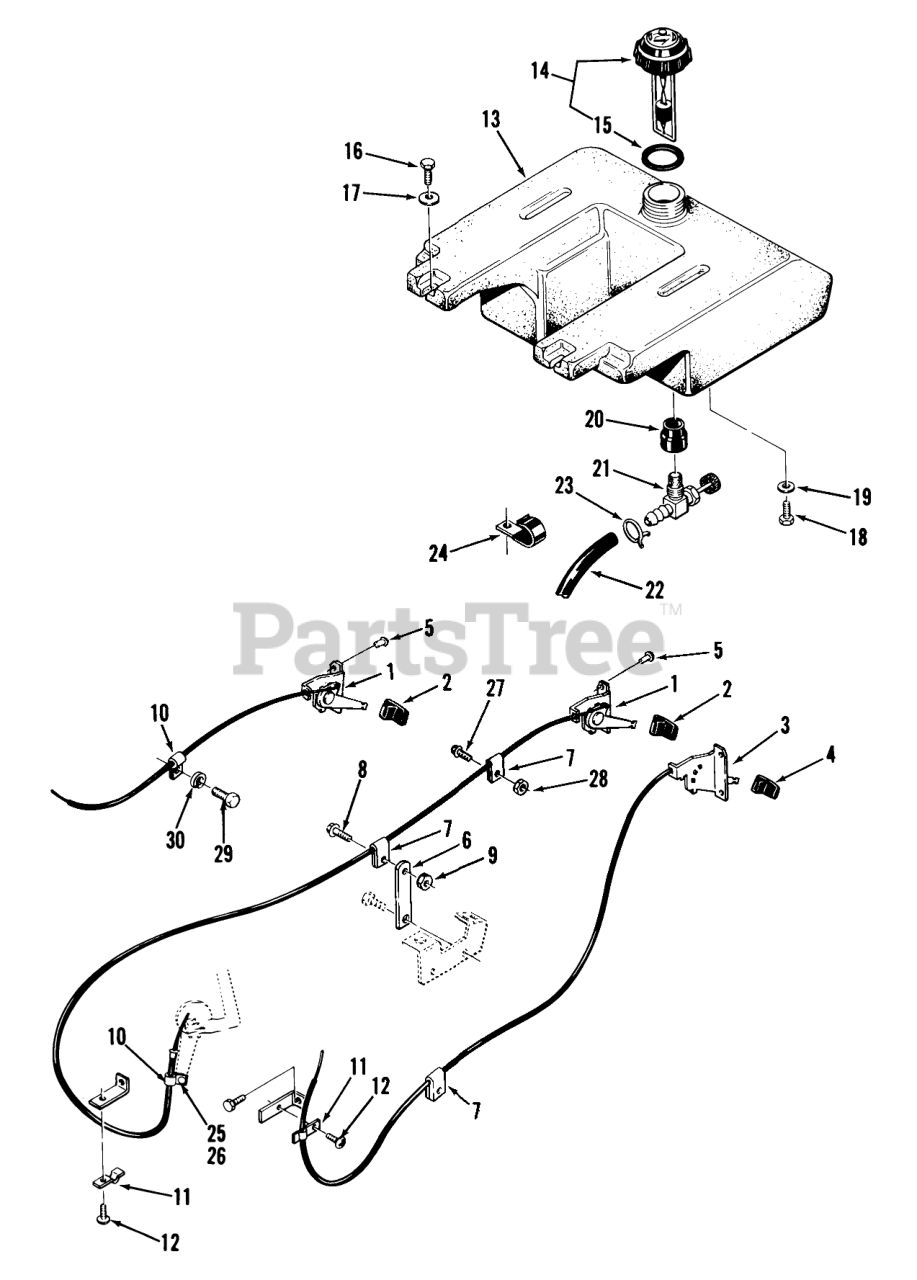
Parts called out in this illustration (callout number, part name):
1	CONTROL-THROTTLE
2	KNOB-THROTTLE
3	CONTROL-CHOKE
4	KNOB-CHOKE
5	RIVET-4
6	Strap
7	THROTTLE CONTROL CLP
8	Screw
9	Nut
10	Clip
11	CLAMP-CABLE
12	SCREW
13	TANK-FUEL
14	ASSY-GAUGE CAP
15	GASKET-GAS CAP
16	Bolt
17	Washer
18	Bolt
19	Lockwasher
20	BUSHING
21	VALVE-FUEL
22	Fuel Line C-85 Only
22	Fuel Line
23	Clamp
24	CLIP
25	Screw
26	Nut
27	Screw
28	Nut
29	Bolt
30	Washer
